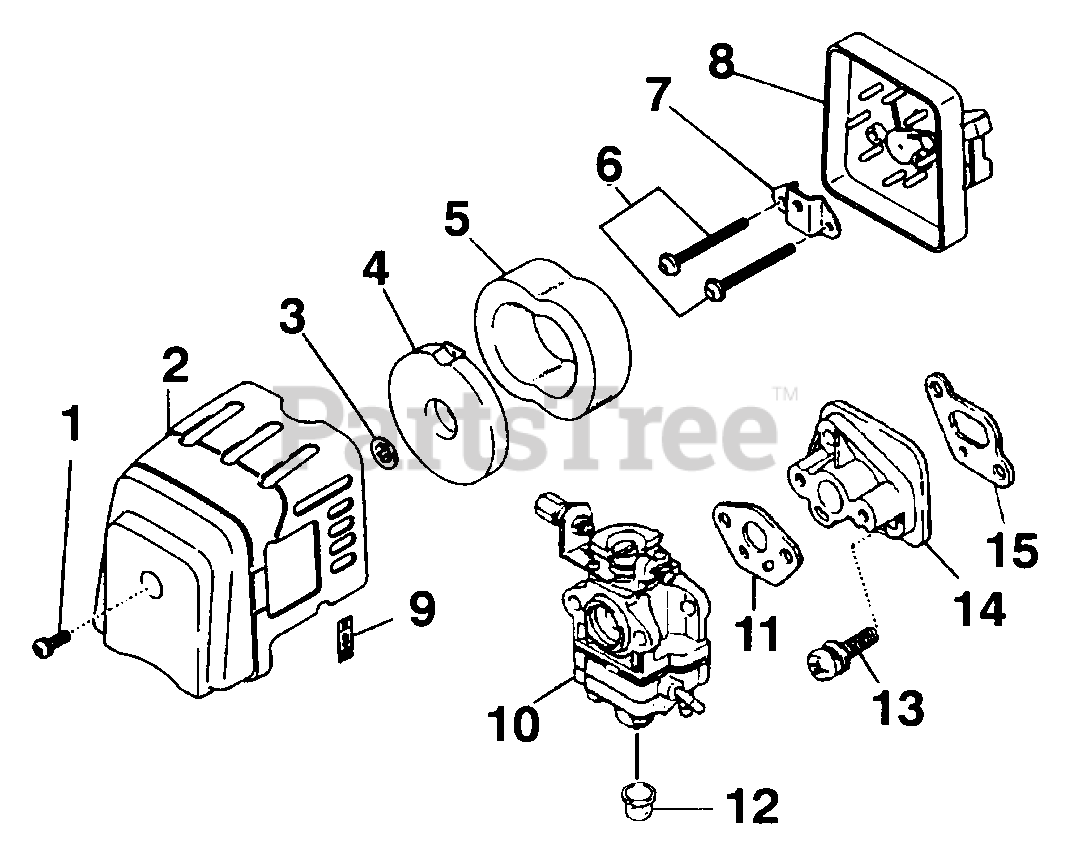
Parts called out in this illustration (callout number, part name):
1	Screw & Washer
2	Cover, Cleaner
3	Pal Nut
6	Screw & Washer
8	Base, Cleaner
9	Label, Choke
10	Carburetor
11	Gasket, Carburetor
12	Primer Bulb
13	Screw & Washer
14	Insulator
15	Gasket, Insulator
